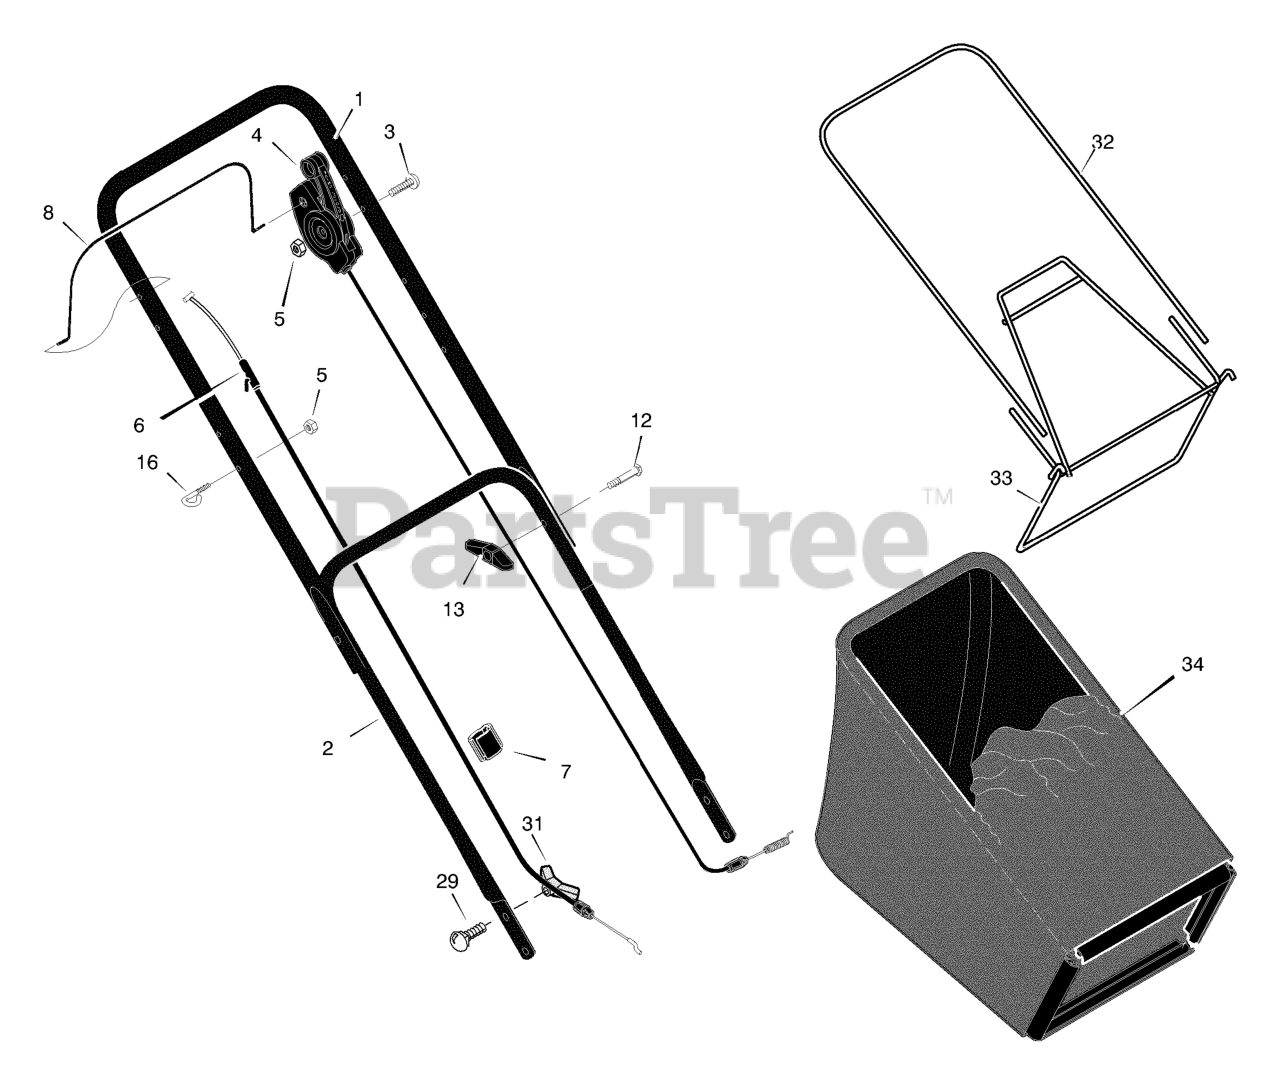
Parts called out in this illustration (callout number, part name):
1	Handle, Upper
2	Handle, Lower
4	Control, Drive
5	Locknut
6	Cable, Stop
7	Fastener, Cable
8	Lever, Stop
13	Knob
16	Guide, Rope
29	Bolt, Carriage
31	Knob, Plastic
32	Tube, Bag
33	Frame Assembly
34	Bag, Cloth
